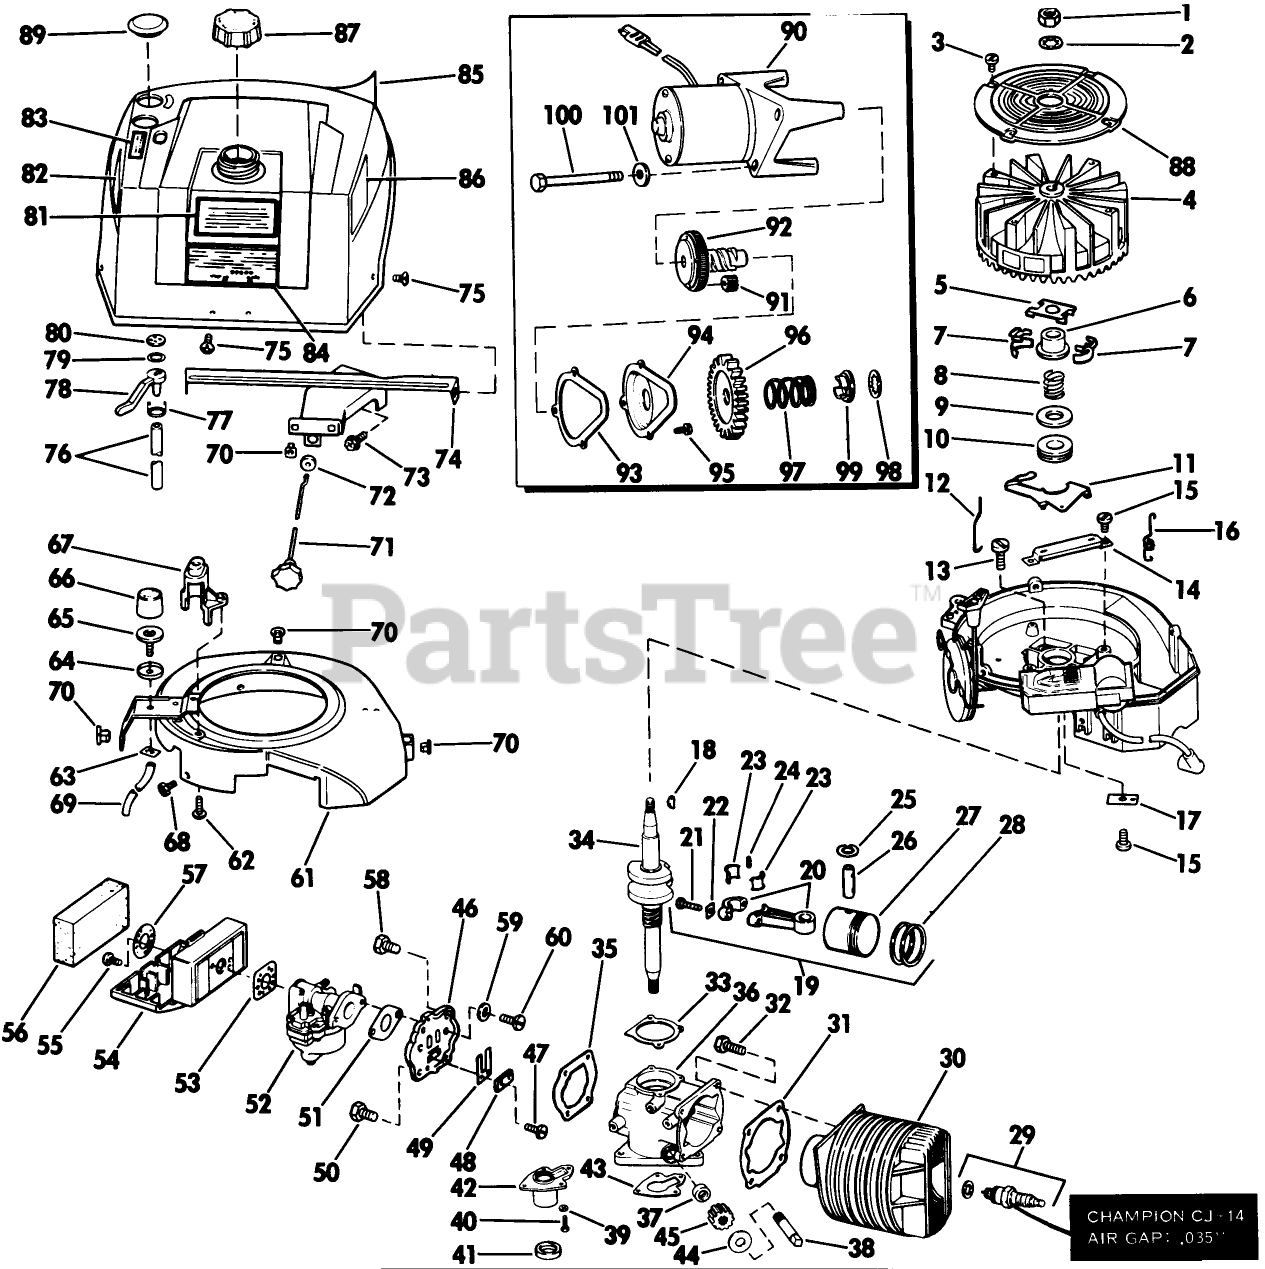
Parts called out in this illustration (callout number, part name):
3	SCREW F
6	COLLAR S
8	SPRING S
11	LEVER-GOVERNOR S
14	BRACKET
15	SCREW S
23	LINER ASM
25	RING-RETAINING
29	Spark Plug
31	GASKET S
33	GASKET S
35	GASKET S
43	GASKET-CVR S
44	THRUST WASHER
46	REED PLATE AY. S
48	PLATE-BACKUP, REED
50	SCREW S
51	GASKET S
53	GASKET S
55	SCREW S
56	AIR FILTER S
57	WASHER S
58	SCREW S
63	LOCKNUT S
64	CUP-BULB
70	NUT-CLIP
73	SCREW S
74	BRACKET
75	SCREW S
79	WASHER S
